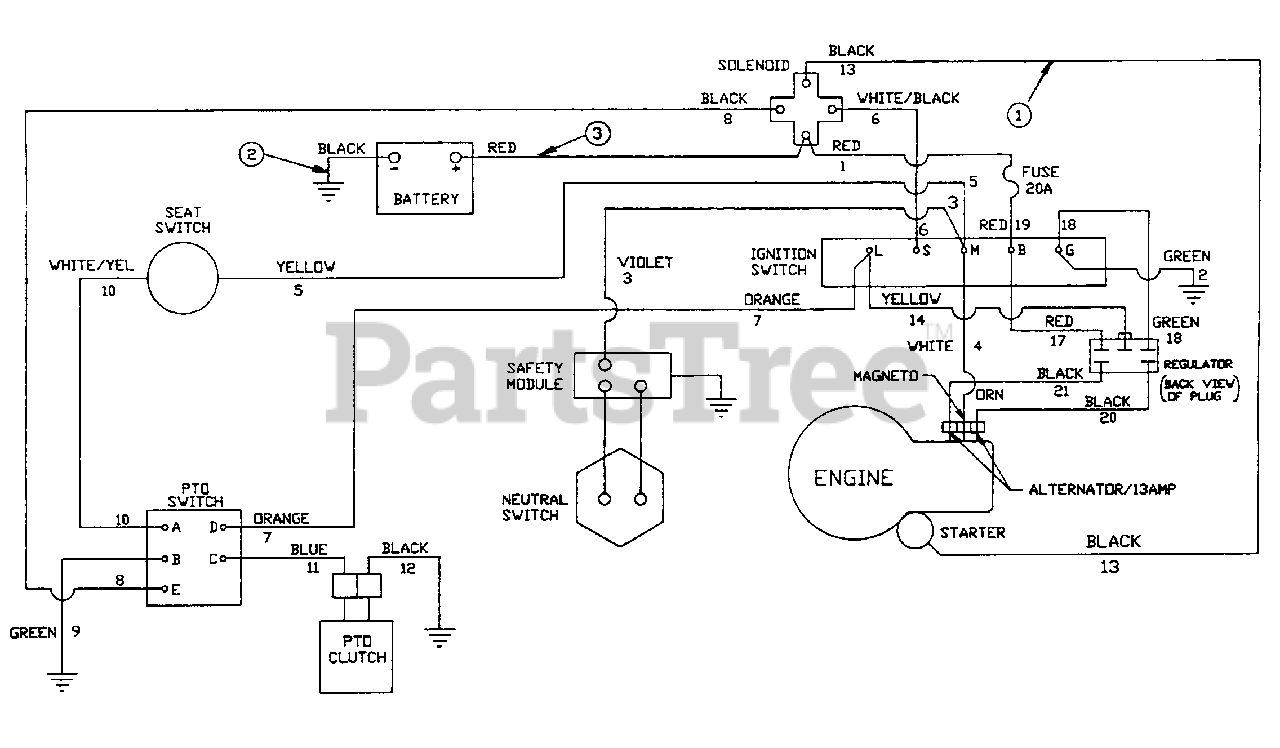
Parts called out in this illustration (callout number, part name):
1	WIRE HARNESS
2	BATTERY CABLE- Ground
3	BATTERY CABLE
